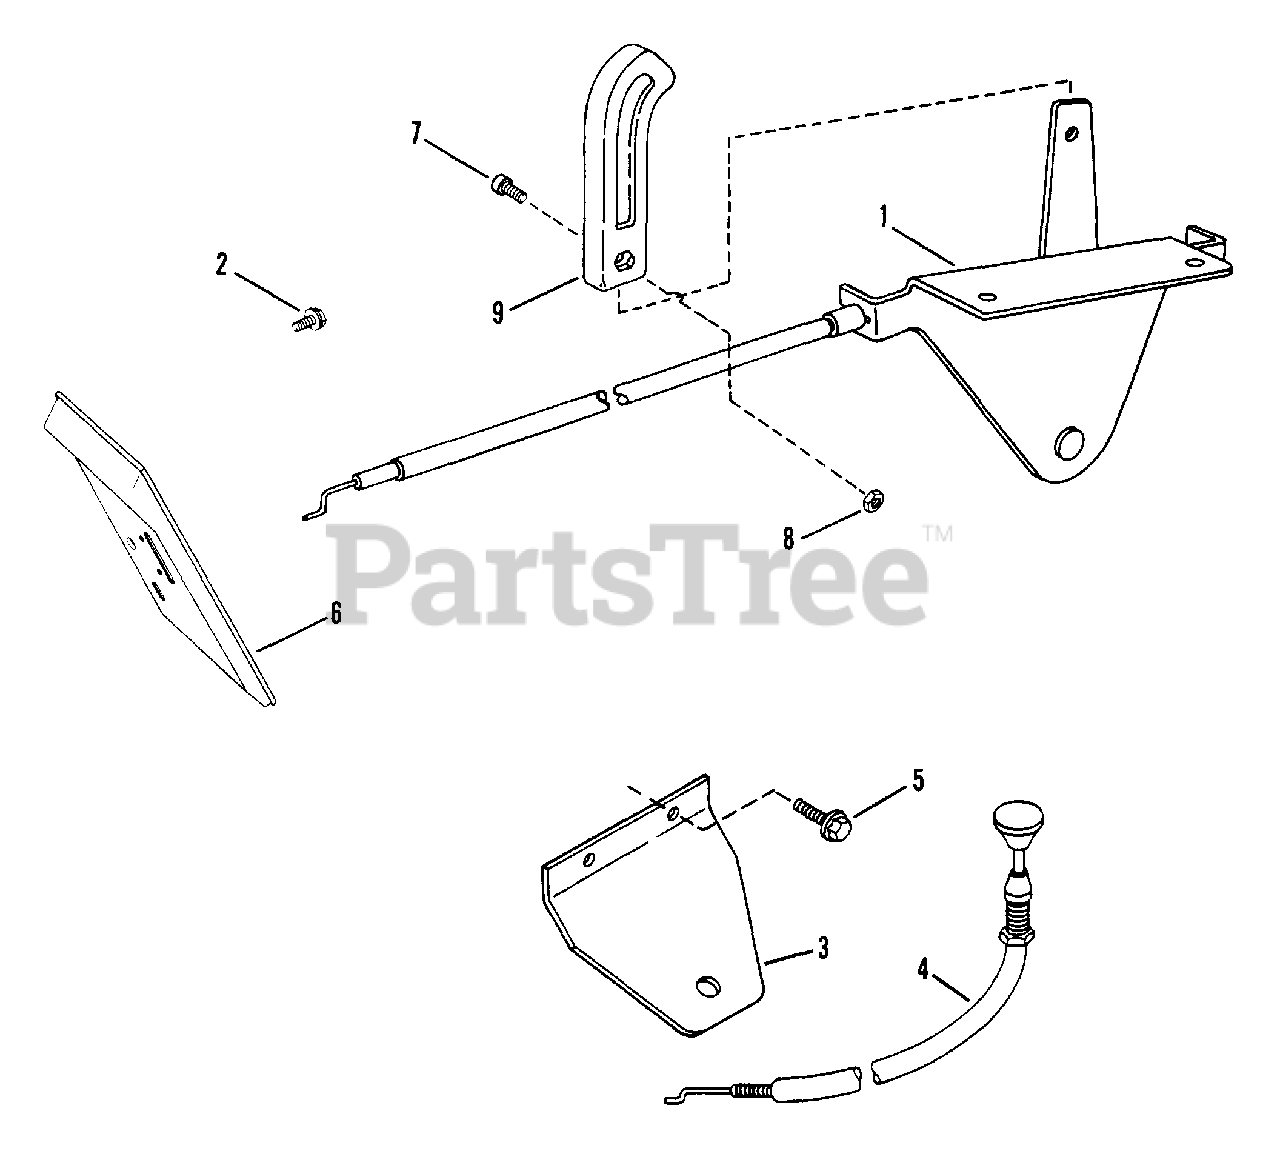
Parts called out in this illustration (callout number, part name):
1	CONTROL, Throttle
2	SCREW, #10-24 x 1/2" Self-Tapping
3	PLATE, Throttle Control
4	CONTROL, Choke
5	SCREW, 1/4-20 x 5/8" Self-Tapping
6	COVER, Dash Panel
7	SCREW, #8-32 x 3/8" Cross Recess Filister
8	NUT, #8-32 Hex
9	KNOB, Throttle Control
